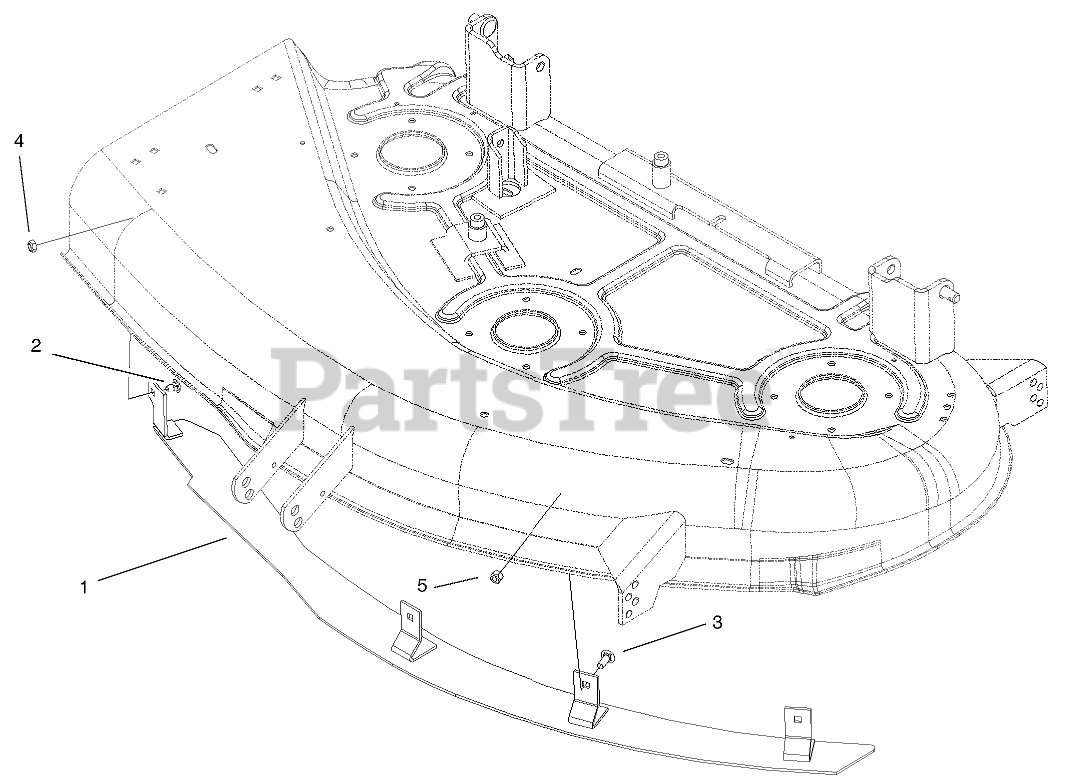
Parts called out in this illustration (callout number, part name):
2	SCREW-CARR
3	SCREW-CARR
4	NUT-LOCK, NI
5	NUT-LOCK, NI
